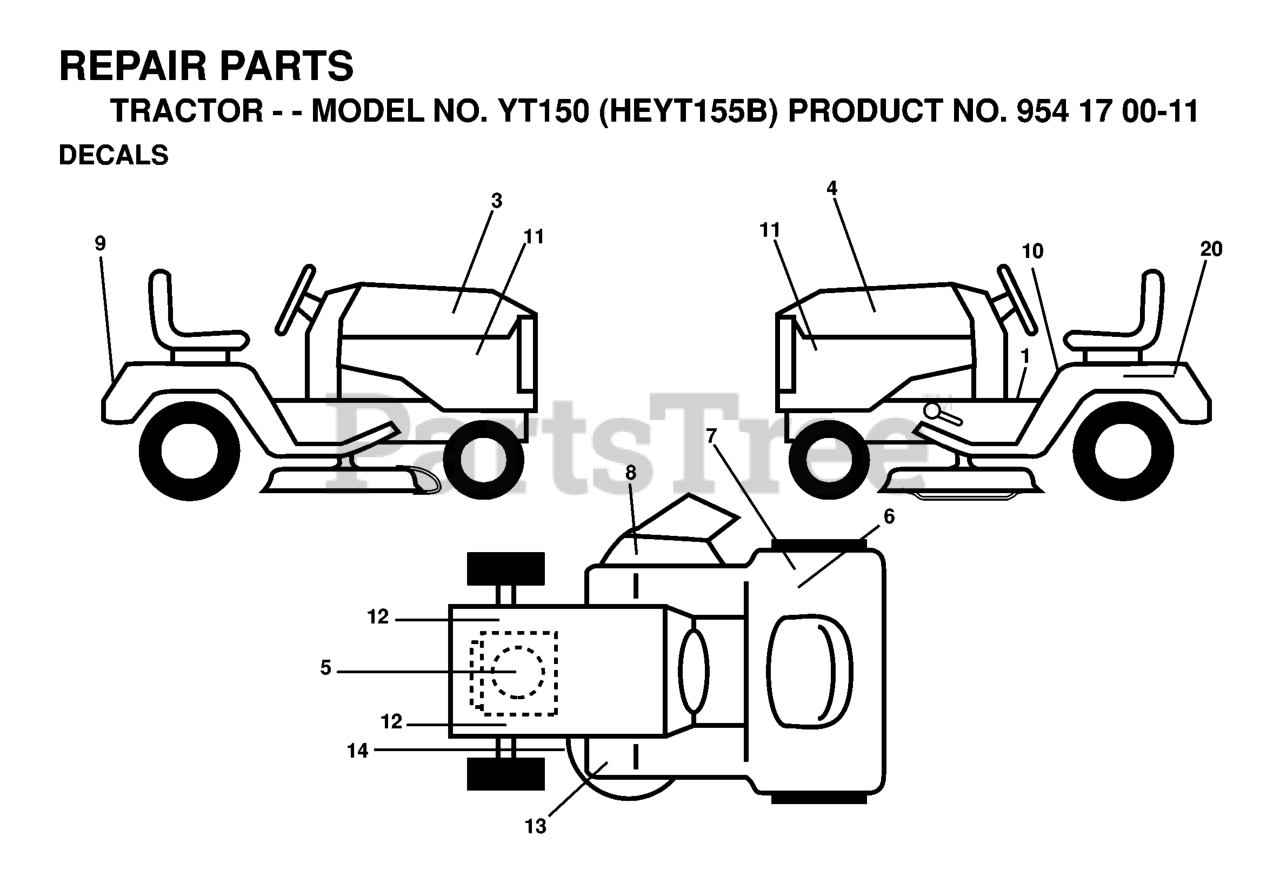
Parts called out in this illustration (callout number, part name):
1	DECAL PARK BRAKE
3	Decal Hood RH
4	Decal Hood LH
5	DECAL
6	DECAL CERTIFICATION
7	DECAL EUROPE STANDARD CE
8	DECAL MOWER CUT/FINGER
9	DECAL FENDER HUSQ
10	DECAL READ OWNER'S MAN SYMS
11	DECAL PNL SIDE
12	DECAL
13	DECAL
14	DECAL V BELT SCHEMATIC
20	DECAL BTRY SYMBOLS
